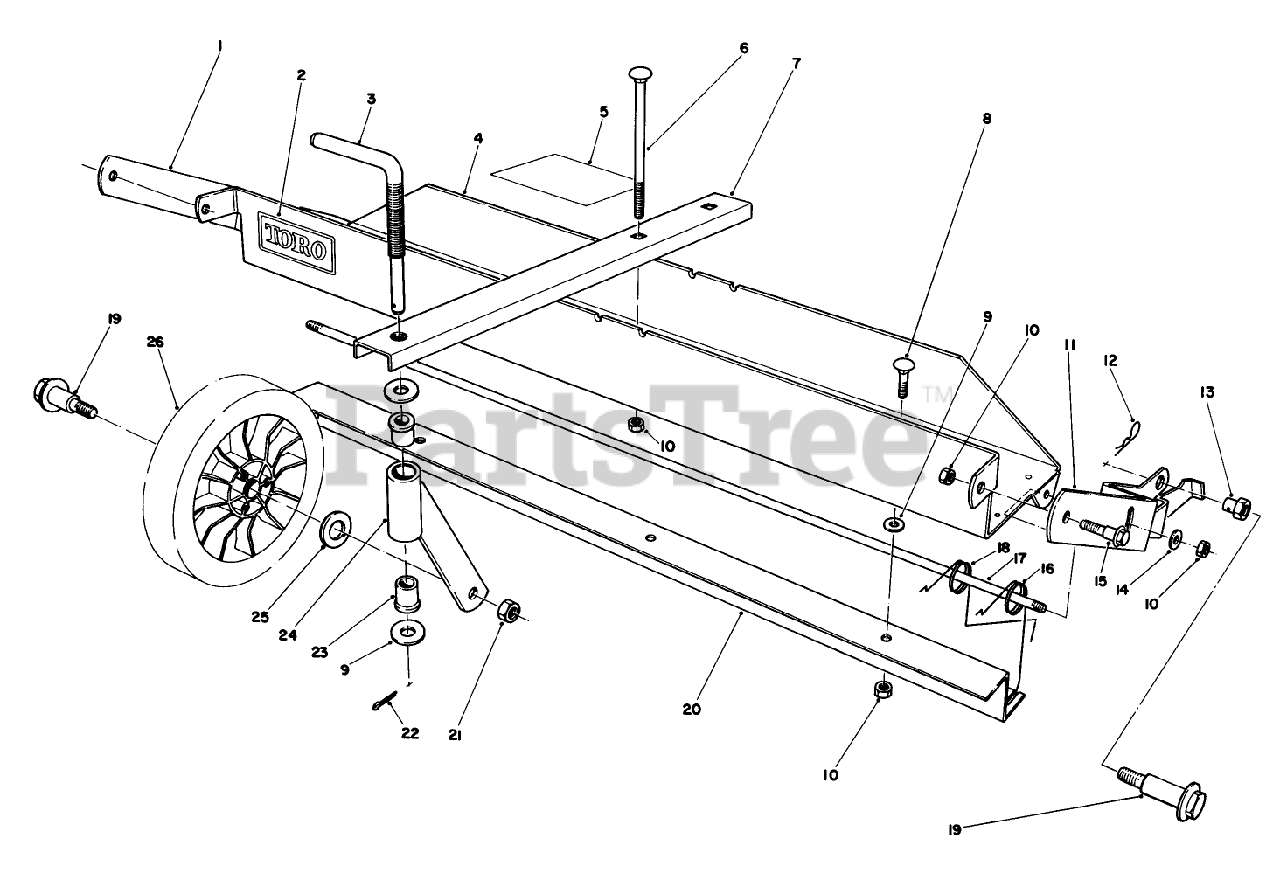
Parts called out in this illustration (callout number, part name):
3	CASTOR ADJ ROD
6	SCREW-CARR
8	BOLT-CARR
9	WASHER-PLAIN
10	NUT-HEX, SIDE DEFORM
11	Frame Mount-L.H.
12	PIN-COTTER, HAIR
13	PIVOT NUT
14	WASHER-FLAT
15	BOLT-SHOULDER,HFH
18	DETHATCHER SPRING
19	BOLT-WHEEL
20	SPRING GUIDE STRAP
21	NUT-LOCK
22	PIN-COTTER
25	WASHER
